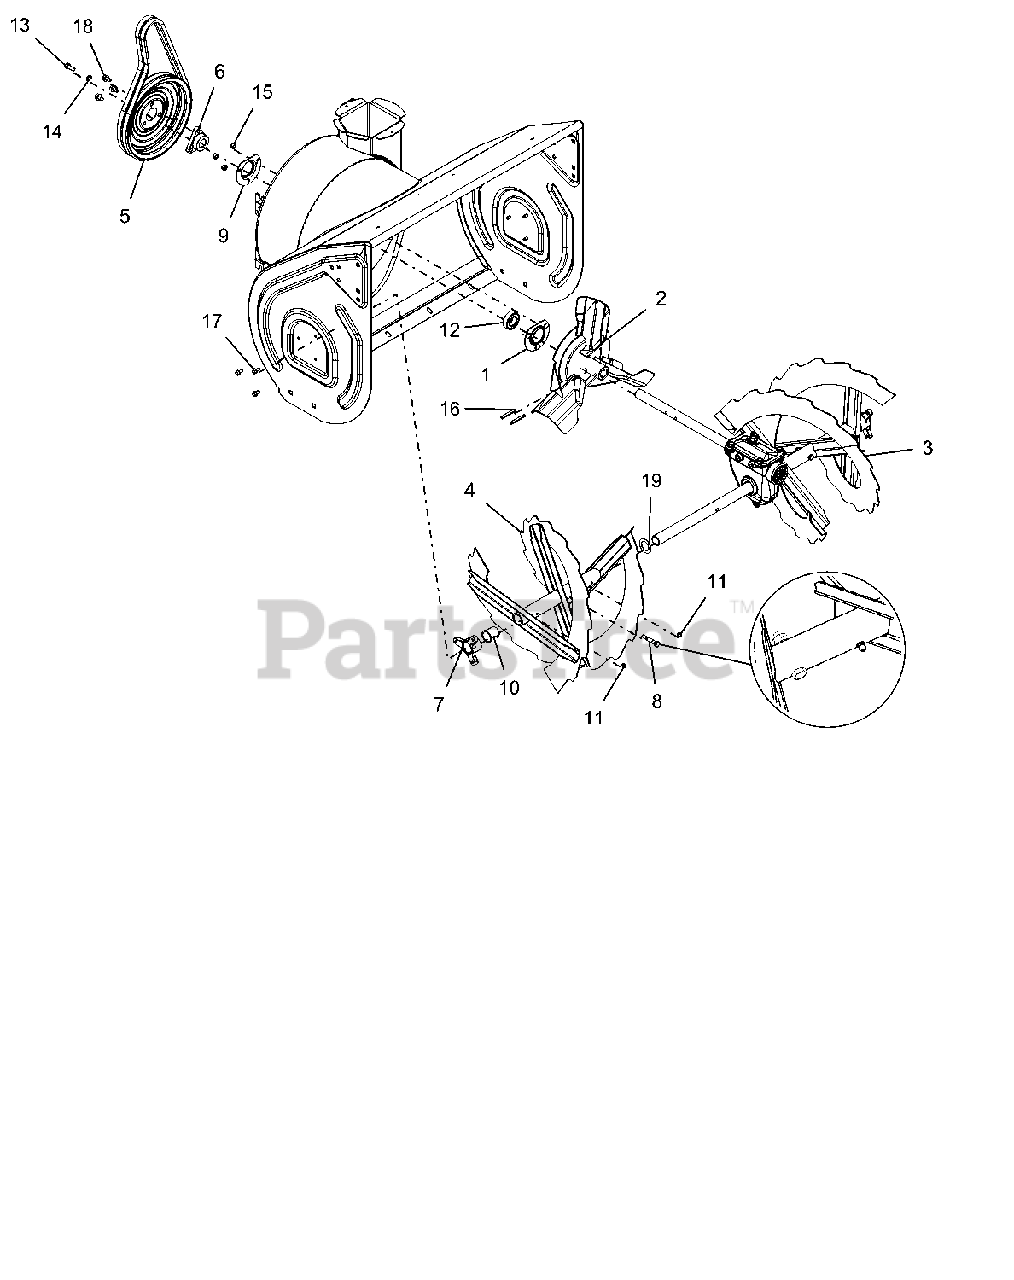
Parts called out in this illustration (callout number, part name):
1	BEARING FLANGE
2	IMPELLER, 3 BLADE-14"
3	RAKE, LH-28"(1 ID X 15.75 OD)
4	RAKE, RH-28"(1 ID X 15.75 OD)
5	PULLEY, SPIN FORM DUAL GROOVE
6	PULLEY HUB, D-BORE .87 PRO
7	BUSHING, RAKE SHAFT 1"
8	SHEAR BOLT SERVICE ASSEMBLY
9	BEARING FLANGE
10	BSHG-FLG SPLIT NYLINER 1.0" HP
11	ZERK,FITTING .25X.125 DRIVE IN
12	BRG-BALL .876X1.75X.50 RSTFP
13	BLT-HEX .31-24X.75 YWZC GR5
14	WSHR-LK .312X.097 HVY YWZC
15	@NUT-LK-CTR .25-20 YWZC
16	PIN-ROLL .250X1.75
17	SCR-TAP .25-20X.50 HWH TR YWZ
18	@SCR-TAP .31-18X.50 HWH TR YWZ
19	WSHR-FL-STL 1.010X1.505X.062YZ
